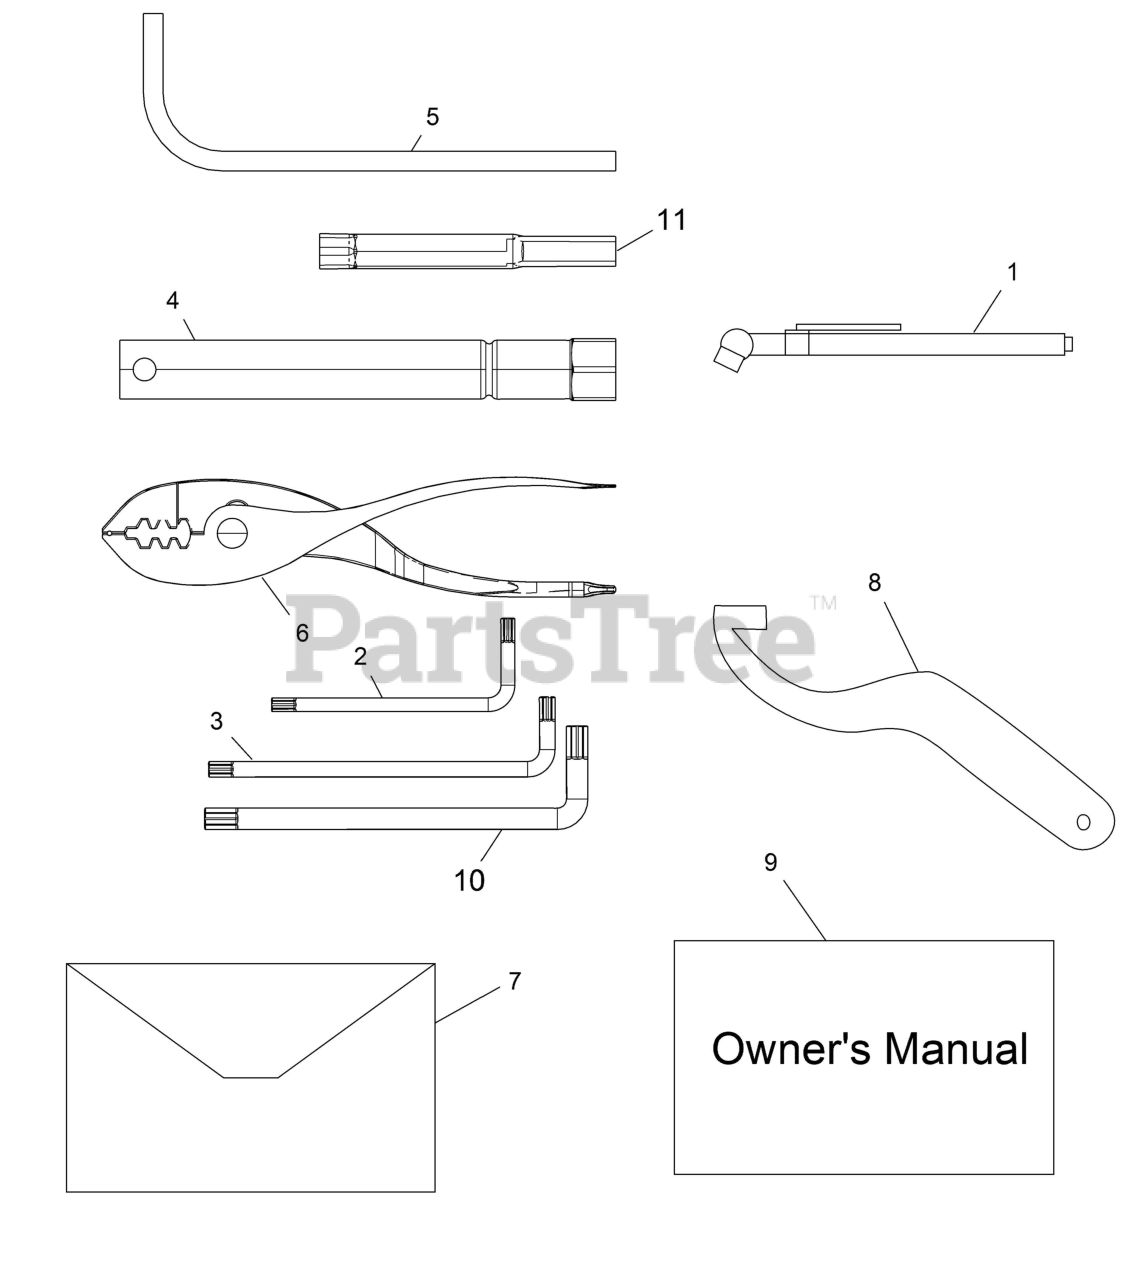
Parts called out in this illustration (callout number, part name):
1	GAUGE-TIRE PRESSURE,30 PSI
2	WRENCH-TORX,T-25
4	SOCKET, SPARK PLUG
5	HANDLE, SPARK PLUG
6	PLIERS-COMBO, #2 ASSEMBLY
7	POUCH,TOOLKIT,9"
8	WRENCH-SPANNER, CAM
9	MAN,OWN,18 ARIENS 1000D CREW
10	WRENCH-TORX,T-40
